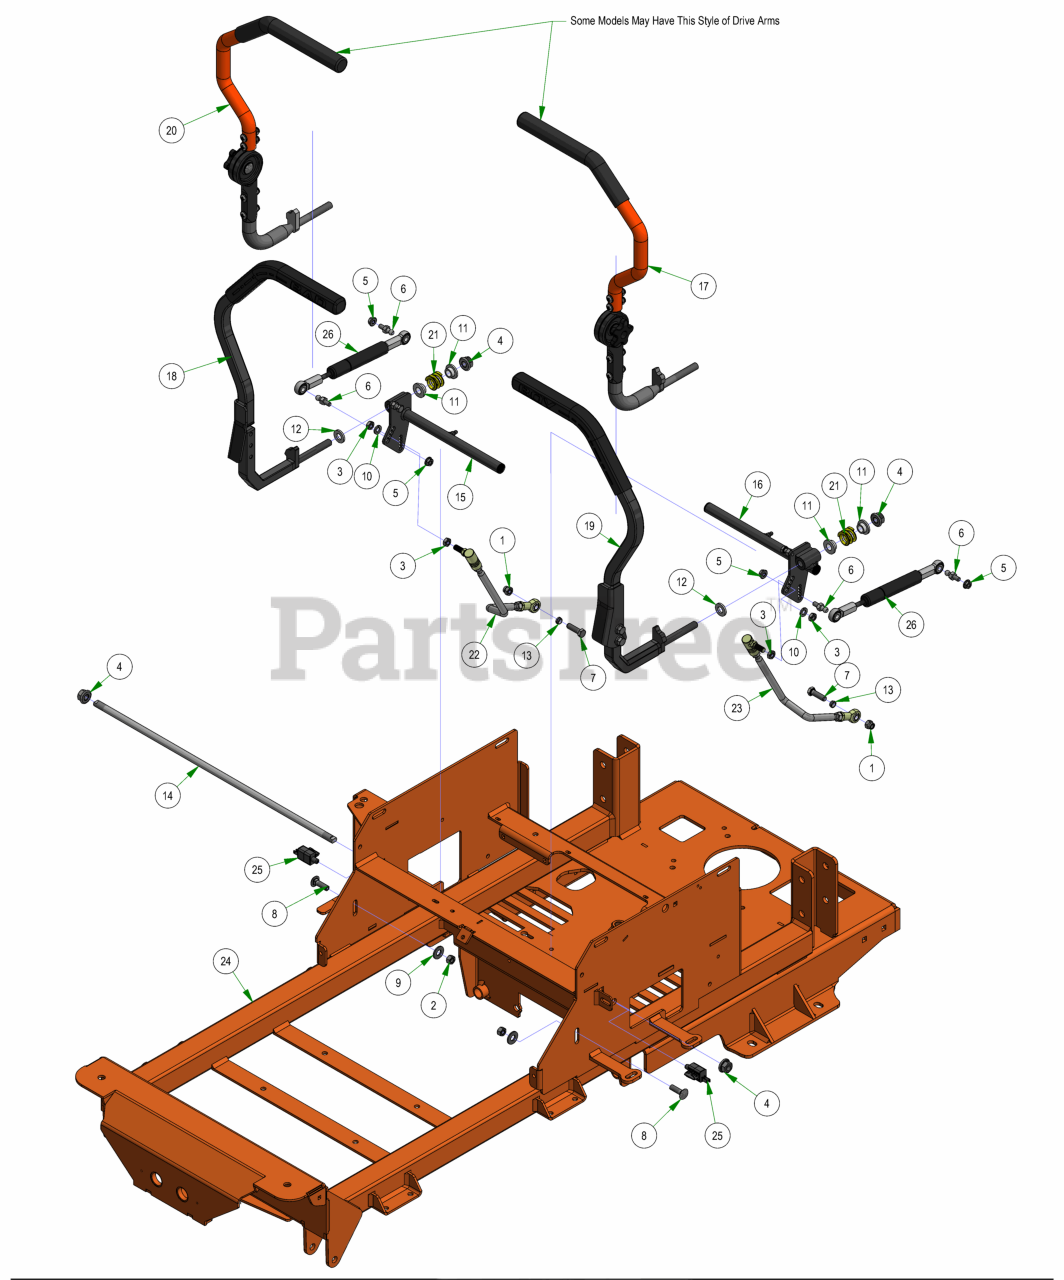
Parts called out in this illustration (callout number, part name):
1	3/8-16 NYLON INSERT LOCKNUT ZINC
2	3/8-16 HEX NUT ZINC
3	3/8-24 HEX NUT ZINC YELLOW
4	1/2-13 NYLON INSERT FLANGE LOCKNUT ZINC
5	5/16-18 HEX SERRATED FLANGE NUT HARD/ZINC
6	10mm Damper Ball Stud-Steering
7	3/8-16 X 1-1/4 HEX CAP SCREW (GR.5) ZINC
8	3/8-16 X 1-1/4 CARRIAGE BOLT ZINC
9	3/8 FLAT WASHER USS (1" OD) ZINC
10	3/8 SPLIT LOCKWASHER ZINC
11	.525 ID SHOULDER WASHER NYLON
12	.505 ID X 1.000 OD X .125 THICK FLAT WASHER NYLON
13	Drive Arm Transaxle Spacer
14	2021 Maverick Steering Actuator Rod
15	2021 Maverick Drive Arm Actuator RH Assembly
16	2021 Maverick Drive Arm Actuator LH Assembly
17	2018 Adjustable Steering Arm - Left
18	Small Mower Square Drive Arm RH Assembly
19	Small Mower Square Drive Arm LH Assembly
20	2018 Adjustable Steering Arm - Right
21	Drive Lever Spring
22	Push Rod-Right
23	Push Rod-Left
24	2025 Maverick Frame
25	Rail Mount Safety Switch
26	Steering Damper
